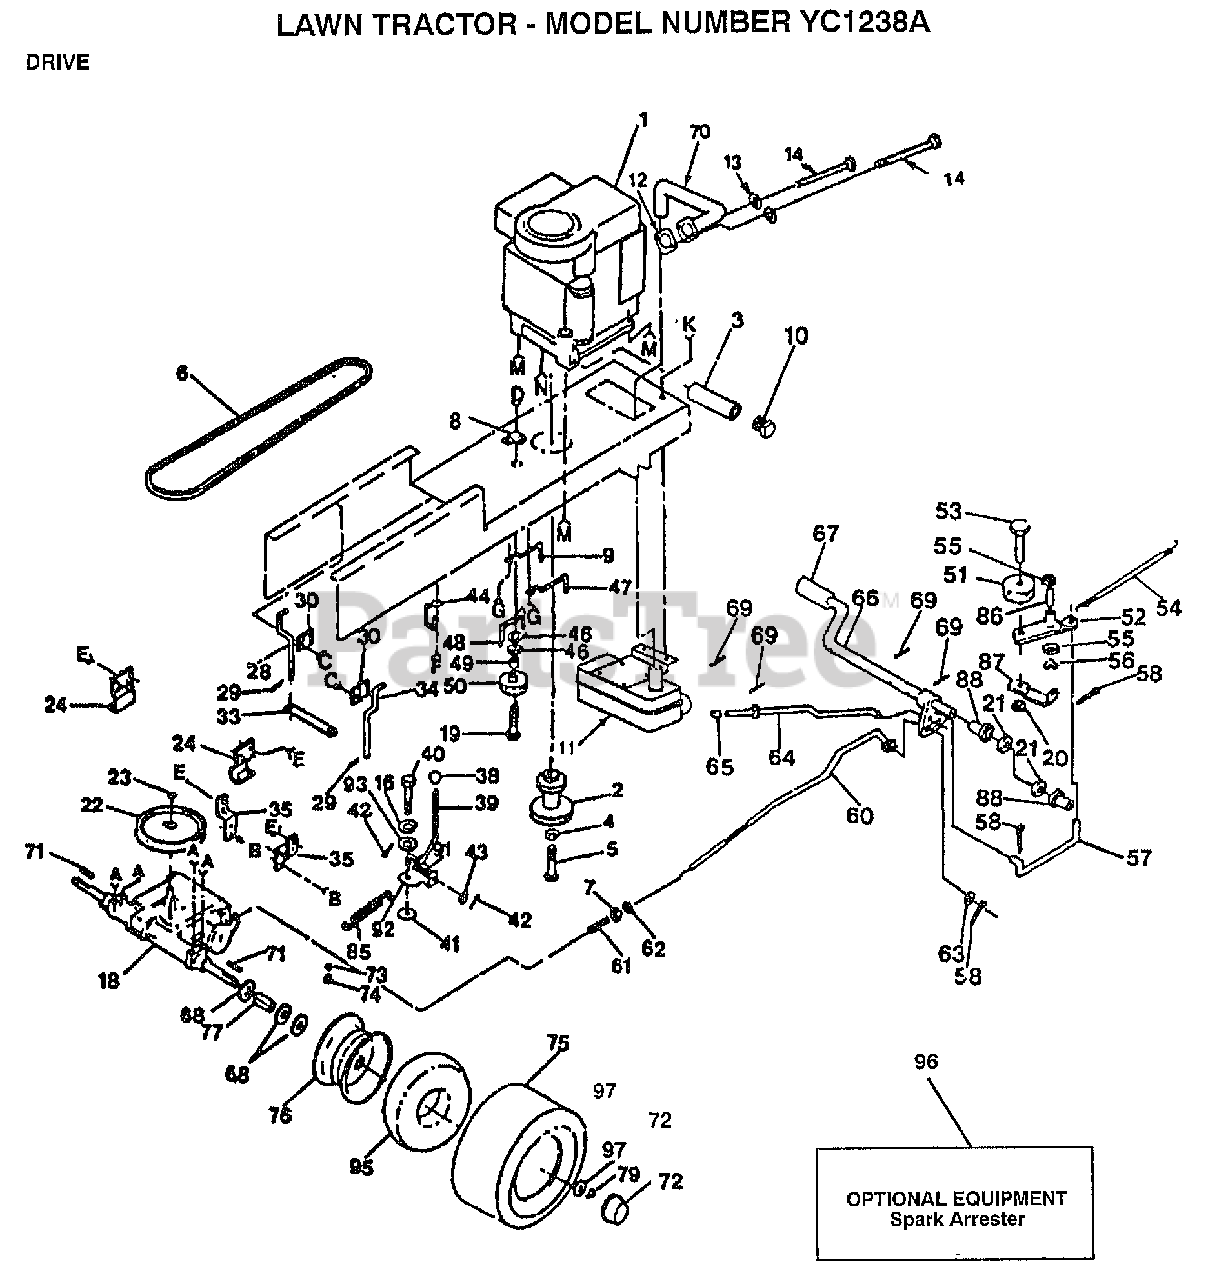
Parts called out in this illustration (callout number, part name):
1	ENGINE BRIGGS AND STRATTON
4	LOCKWASHER
5	BOLT
6	BELT-V.90.0.GD.DR
7	NUT
8	CLIP T
9	KEEPER BELT ENGLH
11	MUFFLER LT
13	LOCKWASHER
14	SCREW LT
15	SCREW
16	LOCKWASHER
19	BOLT
21	WASHER LT
22	PULLEY TRANS
24	BRACKET LT
25	BOLT
26	SCREW
28	KEEPER BELT LH
29	SPRING.RETAINER
30	CLAMP LT
31	BOLT
33	STRAP LOCATOR
34	KEEPER BELTRH
35	STRAP TORQUE
38	KNOB.DUCKHEAD.1/2
39	ROD SHIFTER
41	WASH-SHFT PLT LT
42	PIN COTTER 1/8
43	WASHER
45	SCREW
46	WASHER
47	"KEEPER,BLT ENG LT"
48	BELT KEEPER LT
49	SPACER T
50	PULLEY.IDLER.FLAT
52	ARM IDLER
54	"SPRING, RETURN LT"
55	WASHER LT
56	KLIP RING
57	"LINK, CLUTCH T"
58	COTTER PIN
60	BRAKE ROD LT
61	SPRING ROD LT
62	NUT
63	WASHER
65	PLUNGER CAP T
67	PEDAL COVER T
68	WASHER
70	PIPE EXHAUST
71	SQUARE KEY
72	HUB CAP
73	VALVE CAP
74	VALVE STEM LT
77	SPACER LT
79	E-RING LT
83	WASHER
86	"LY, BEARING"
87	RETAIN BELT
88	NYLON BEARING
91	SPRING LT
92	PLATE SHIFT LT
93	WASHER LT
94	LOCKWASHER
95	TUBE.18X9.5-8
96	SPARK ARREST KIT
97	WASHER
